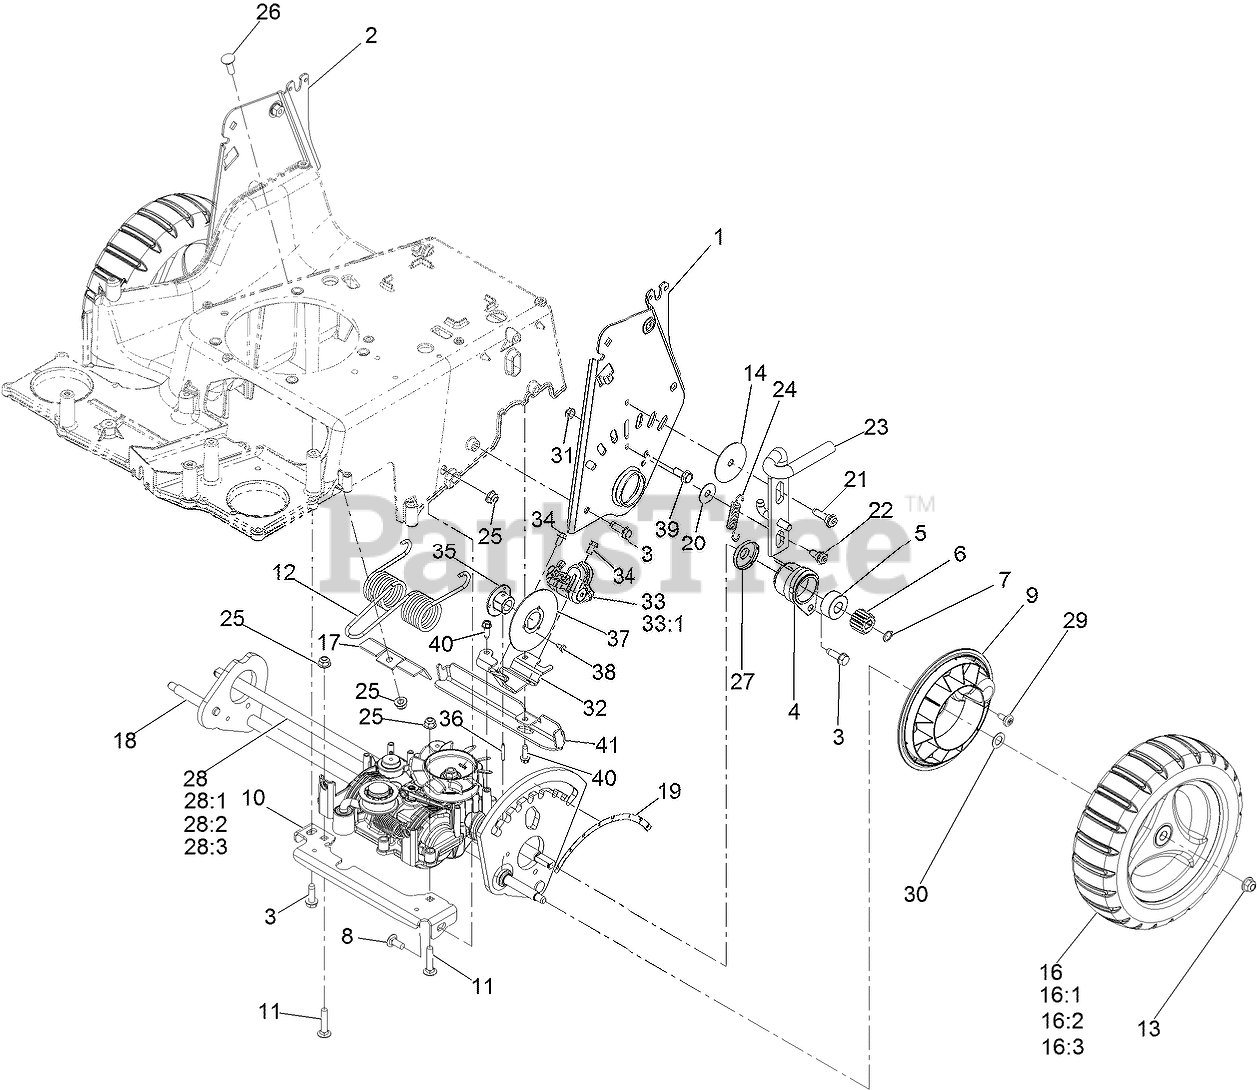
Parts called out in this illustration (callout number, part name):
1	HOC Plate Assembly
2	HOC Plate Assembly
3	SCREW-THD ROLL, HWH
4	Bearing Retainer ASM
5	BEARING-BALL, CUSTOM
6	GEAR-PINION, 15T
7	RING-RETAINING
8	SCREW-CARR
9	Cover-Wheel
10	Bracket-Transmission, Front
11	BOLT-CARR
12	SPRING-TORSION
13	NUT-HF, NI
14	WASHER-PLAIN
16	WHEEL ASM, 10.5 W/GEAR
16:1	WHEEL ASM, 10.5
16:2	Gear-Wheel, 52T
16:3	STUD-DRIVE
17	BRACKET
18	REAR AXLE ASM
19	DECAL-HOC, REAR
21	SCREW-SHOULDER, BHTF
22	BOLT-SHOULDER
23	LOCK-HEIGHT, ADJ
24	Wheel ASM, 10.5 W/Gear
25	NUT-HF, NI
26	BOLT-CARR
27	COVER-BEARING
28	TRANSMISSION-MV702
29	SCREW-SHOULDER
30	WASHER-PLAIN
31	NUT-LOCK, NI
32	Bracket-Mount, Brake
33	CALIPER-BRAKE, DISC
34	SCREW-HWH
35	Hub-Rotor
36	Pin-Roll
37	Disc-Rotor
38	SCREW-TORX PH THD ROLL
40	SCREW-HWHTF
41	Bracket-Support, Cable
